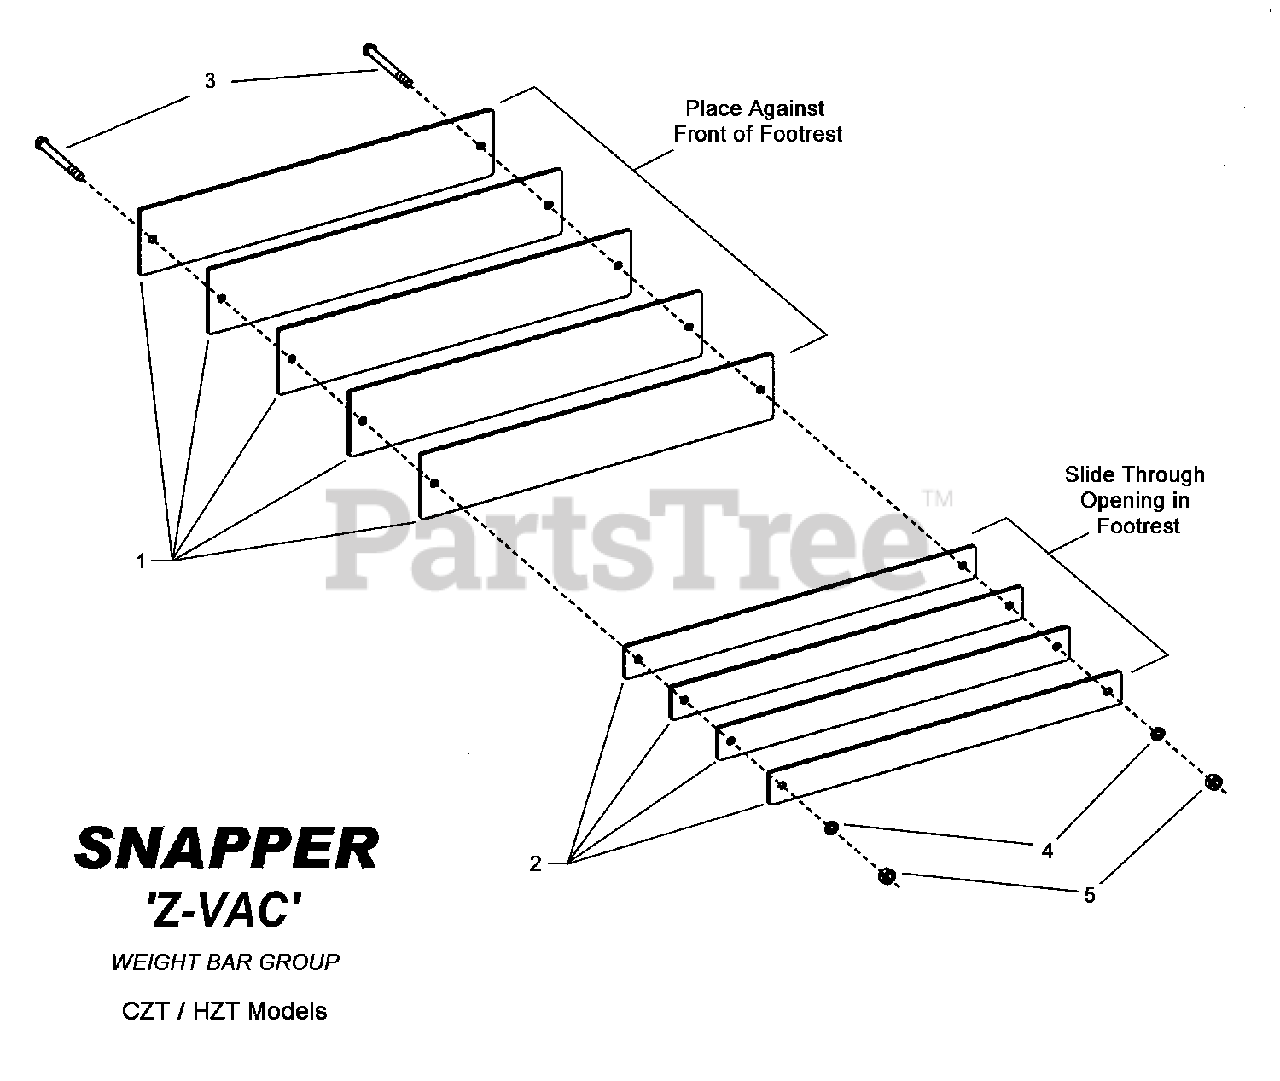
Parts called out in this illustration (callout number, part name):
1	WEIGHT, 27 x 5 x 1/4"
2	WEIGHT, 27 x 2-1/2 x 1/4"
3	BOLT, 1/2-13 x 3 Hex Head
4	WASHER, 1/2 Split Lock
5	NUT, 1/2-13 Hex
